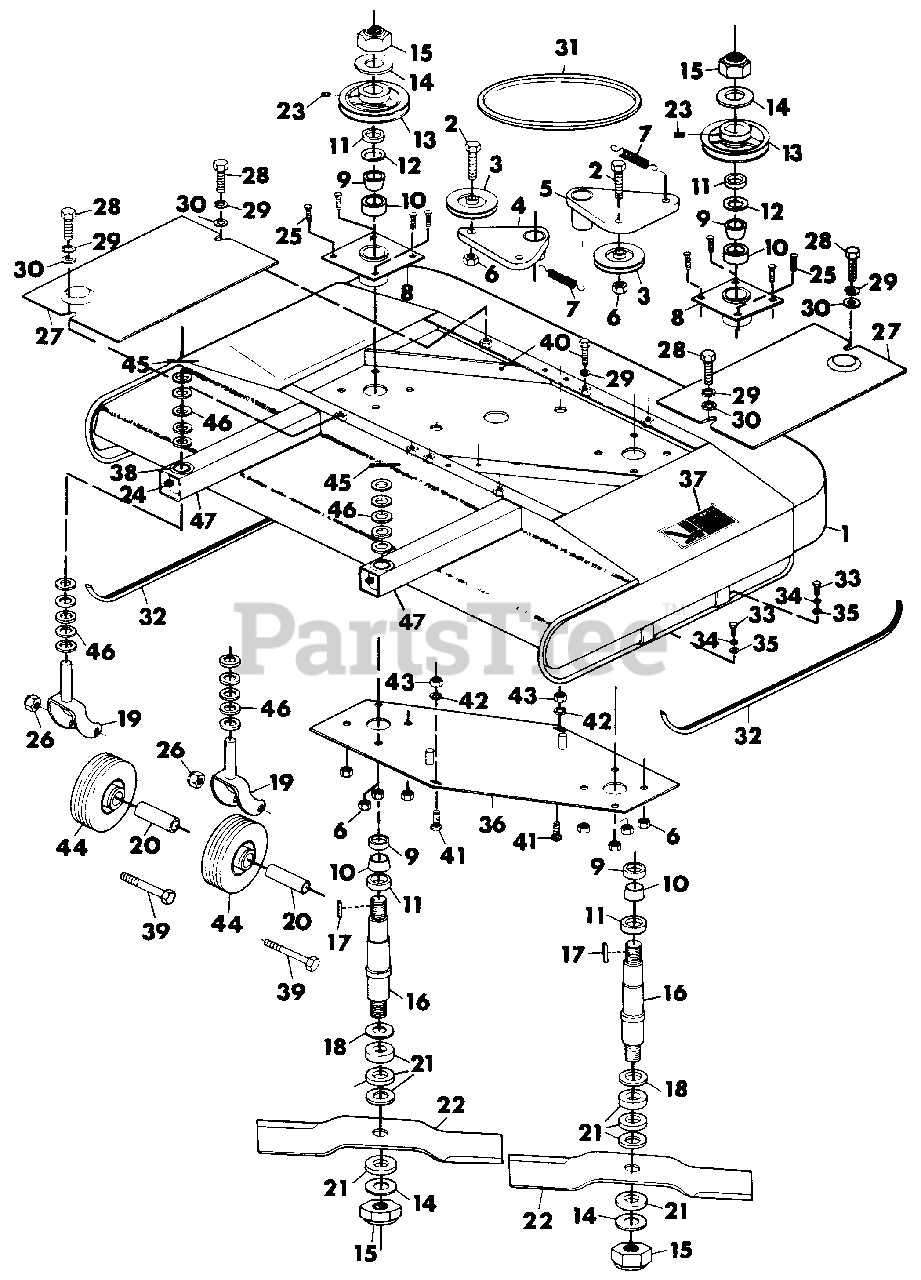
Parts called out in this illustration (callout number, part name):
1	DK,40"COMM.MOWER
2	BLT-HEX .38-16X1.50 GR5 YWZC
3	IDLER
4	WLDMT,ARM IDLER PIVOT
5	WLDMT, ARM IDLER PIVOT
6	NUT-LK-NYL .38-16 YWZC
7	SG-TENS .095X.500X5.5 WLD60 YZ
8	HSG,SPNDL BRG WLDMT
9	ASM,BEARING CUP&CONE
10	ASM,BEARING CUP&CONE
11	SEAL, OIL
12	RING, SEAL
13	PULLEY, ROTOR
14	WSHR-FL-STL .969X2.250X.165
15	NUT-LK .875-9 HT
16	SHAFT, ROTOR
17	KEY, SQUARE .25X1
18	SHIELD, DUST
19	WLDMT, CASTER FORK
20	BUSH.,S.516X.745X2.59 ST
21	CLR,BLADE SPACER 1/4
22	BLADE, MOWER
23	SCR-SET .31-18X.38 SKHCUPDL
24	FTG,LUBE, .25-28 SELF THREAD
25	BLT-RDHDSHSQNK.38-16X1.0 G5YZ
26	NUT-LK-NYL .50-13 YWZC
27	CVR,BELT
28	BLT-HEX .38-16X.625
29	WSHR-LK .38X.094 REG YWZC
30	WSHR-FL-STL.406X.812X.065 YWZ
31	BELT,V 1/2 X 5/16 X 37.5
32	SKID
33	BLT-HEX .31-24X.875 YW ZC
34	WSHR-LK .31X.078 REG YWZC
35	WSHR-FL-STL.344X.688X.065YWZC
36	SPRT,DECK WELDMENT
37	DECAL, DANGER FOOT
38	BSHG-SLV .752X.877X.75 BRONZE
39	BLT-HEX .50-13X3.75 GR5 YWZC
40	BLT-HEX .38-16X1.00 GR5 YWZC
41	BLT-RDHDSQNK .50-13X3.00 G5YZ
42	WSHR-LK .50X.125 REG YWZC
43	NUT-HEX .50-13 YWZC
44	WHL-CASTER
45	PIN-CTR .12X1.50 EXTPRSQCT YZ
46	WSHR-FL-STL.812X1.50X.135YWZC
47	SPRT,GAUGE WHEEL
